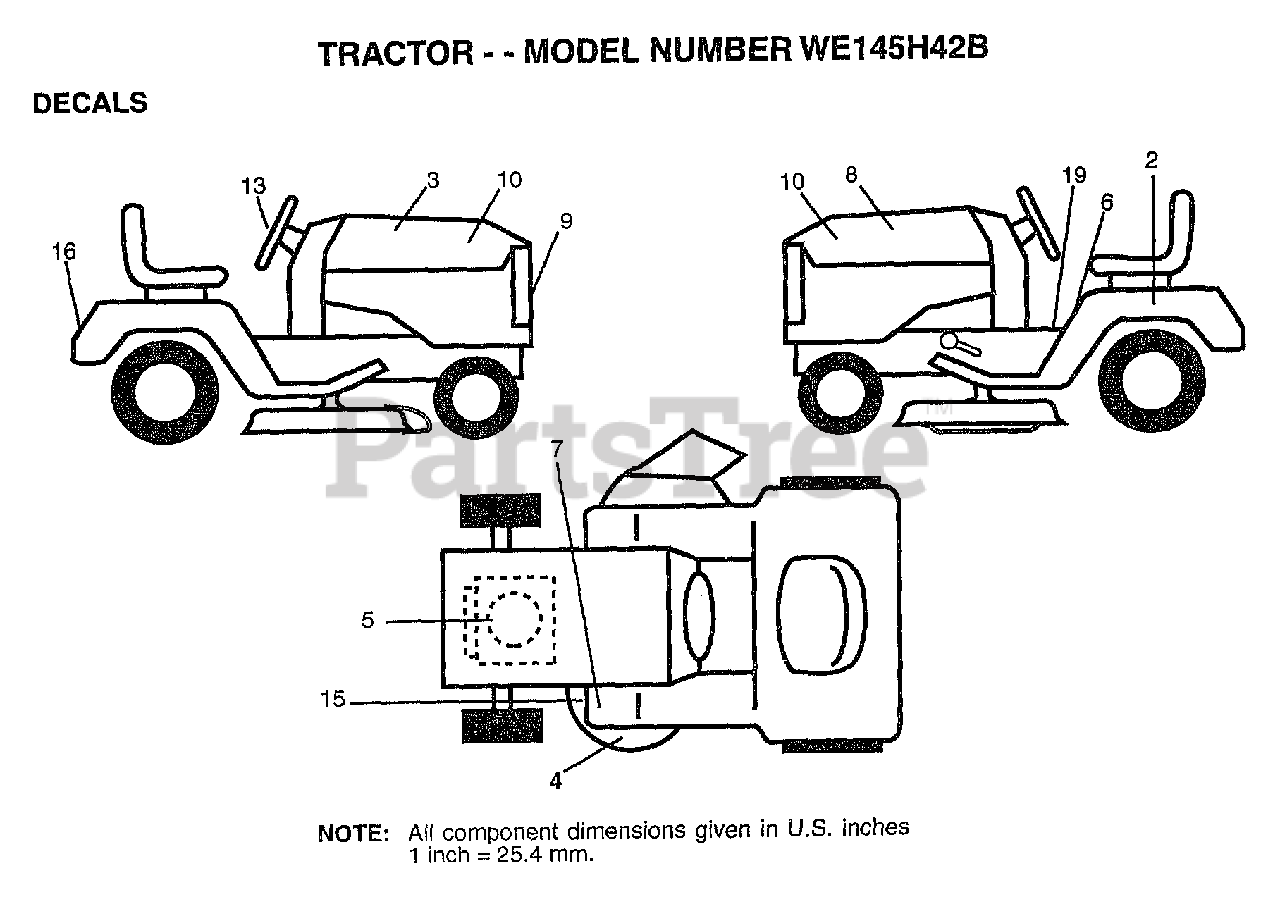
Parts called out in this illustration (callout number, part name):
2	DECAL.BATRY.3-3908
3	"DECAL HOOD,RH"
5	DECAL, ENGINE
6	"DECAL DANGER,FEND"
8	DECAL HOOD LH
9	"DECAL GRILLE,LENS"
10	"DECAL.PANEL,SIDE"
13	"DECAL INS,STRG WH"
15	DECAL
16	"DECAL-SCHEM,BELT"
19	"DECAL INST,SADDLE"
